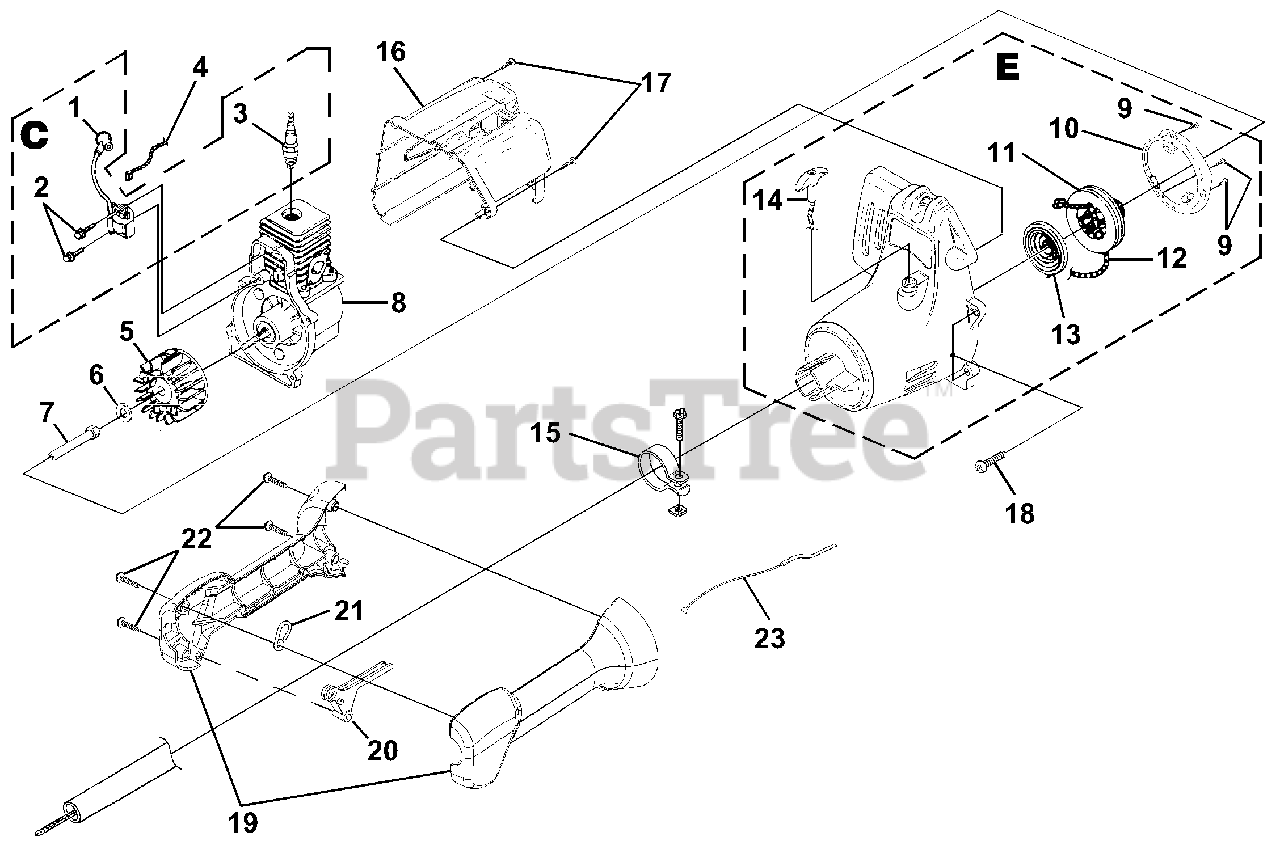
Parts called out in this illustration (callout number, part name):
1	TERMINAL & COVER
2	SCREW-Taptite (8-32 X 1")
3	SPARK PLUG
4	LEAD-Electrical
5	ROTOR KIT
6	WASHER-Flat
7	CONNECTOR-Drive (.250)
8	SHORT BLOCK
9	SCREW-Taptite (8-16 X 1/2")
10	BAFFLE-Air
11	PULLEY-Starter
12	ROPE-Starter (42")
13	SPRING & CONTAINER
14	GRIP-Starter
15	CLAMP w/fasteners
16	HOUSING-Rear Kit
17	SCREW-Taptite (10-14 X 7/8")
18	SCREW-Taptite (10-24 X 3/4")
19	CONTROL HANDLE ASSY.
20	TRIGGER-Throttle
21	HOOK-Harness
22	SCREW-Taptite (10-14 X 7/8")
23	CABLE-Throttle
C	IGNITION KIT
E	COMPLETE STARTER ASSEMBLY
